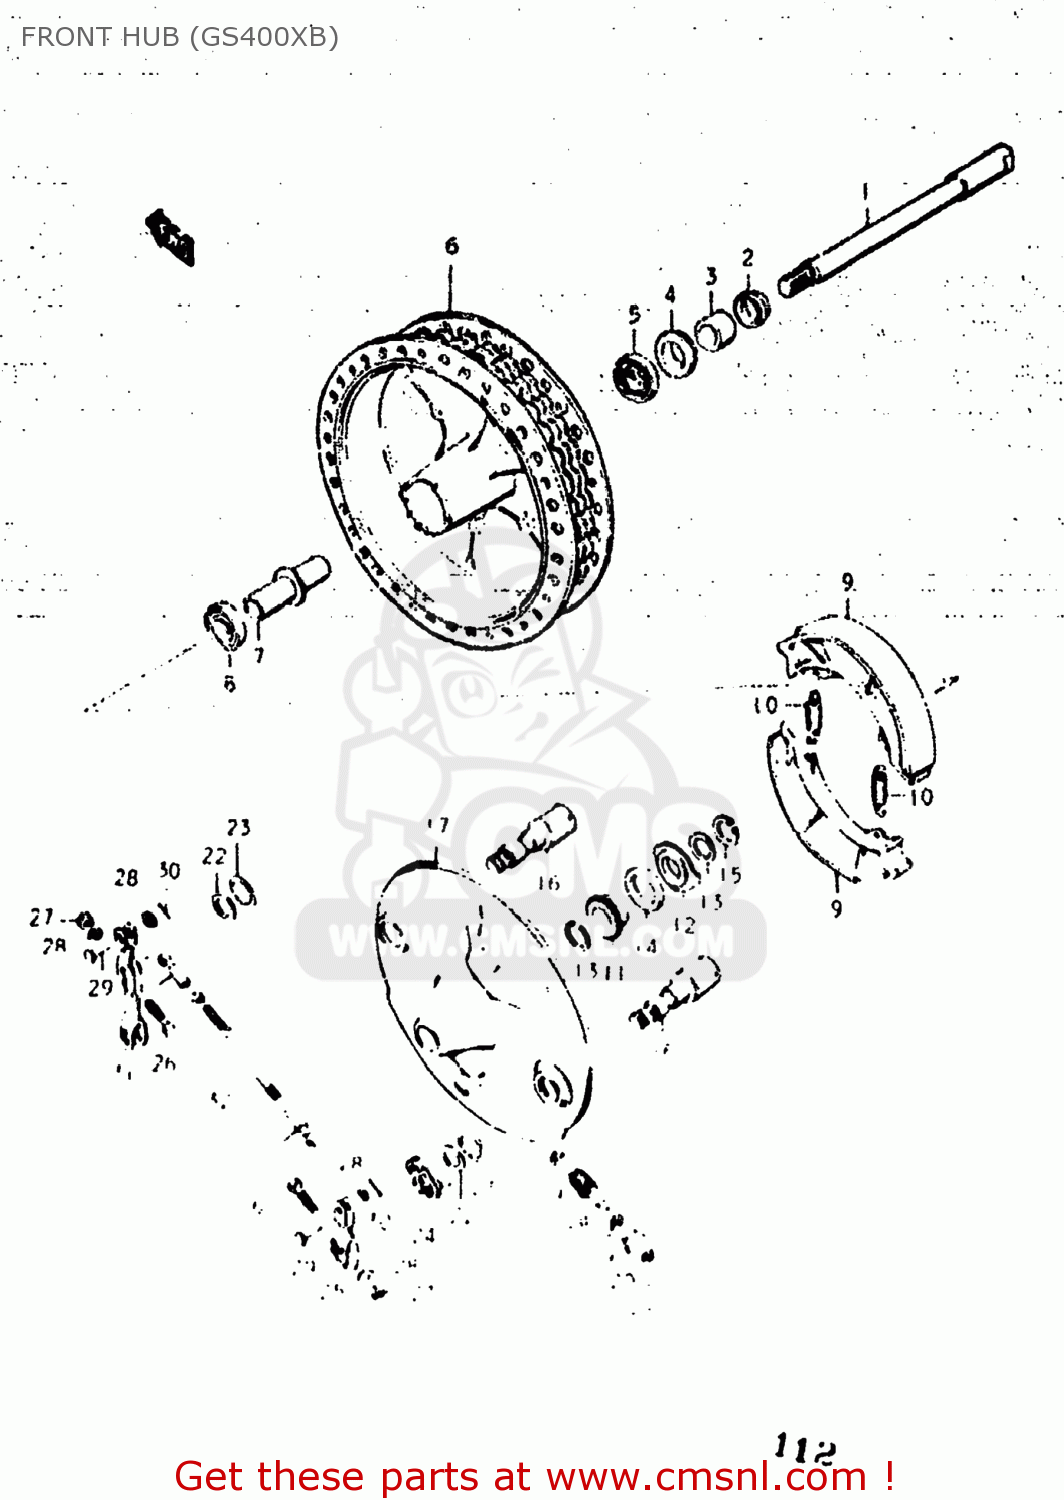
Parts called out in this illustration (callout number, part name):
1	AXLE,FRONT
2	DUST SEAL,FRONT HUB DRUM
3	SPACER
4	OIL SEAL
5	BEARING
6	HUB,FRONT
7	SPACER,FRONT HUB BEARING
8	BEARING
9	SHOE,BRAKE (MCA)
10	SPRING,BRAKE SHOE
11	GEAR,SPEEDOMETER
12	DRIVER,SPEEDOMETER GEAR
13	WASHER(22.5X27X1)
14	OIL SEAL
15	CIRCLIP
16	CAM,FRONT BRAKE
17	PANEL,FRONT HUB
18	PINION,SPEEDOMETER
19	WASHER (5.1X9X0.4)
20	BUSHING,SPEEDOMETER PINION
21	SEAL,OIL(6X10X3)
22	WASHER (15X24X1.6)
23	O-RING,BOSS
24	SPRING
25	LEVER,FRONT BRAKE CAM
26	BOLT
27	NUT
28	WASHER
29	PIN
30	PIN 12X10
31	LEVER,FRONT BRAKE CAM
32	SHOE SET,BRAKE (NAS)
